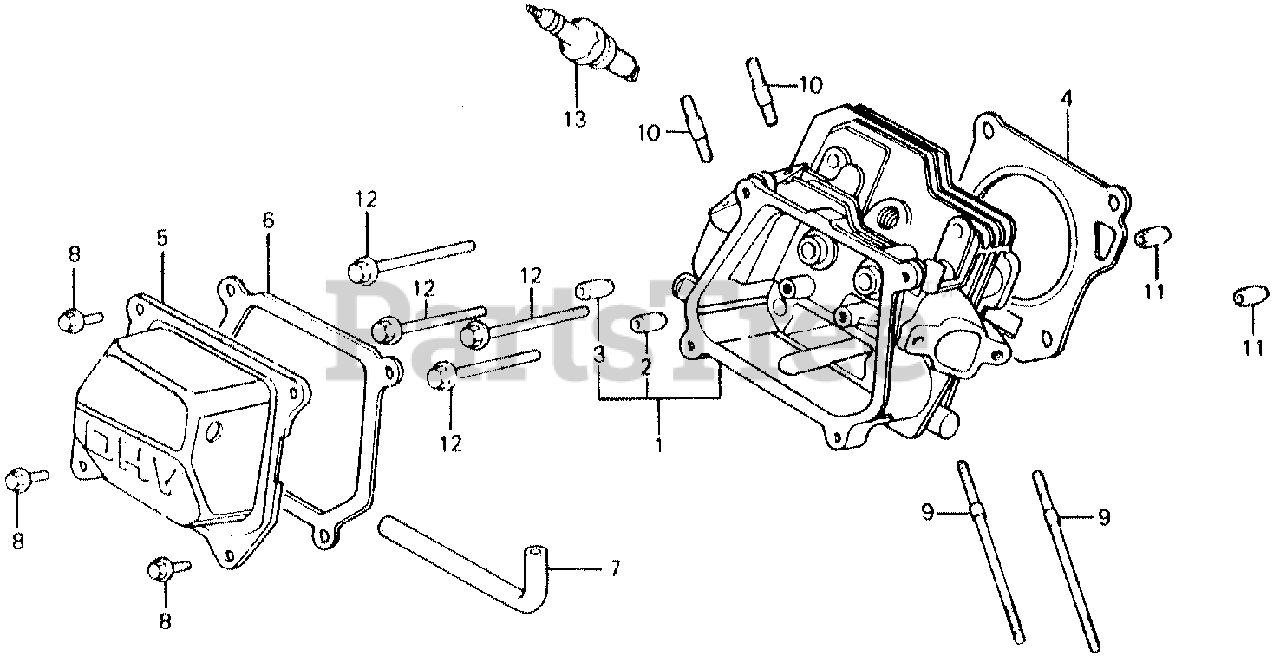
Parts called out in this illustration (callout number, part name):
1	CYLINDER HEAD
2	GUIDE, VALVE (OS)
3	GUIDE, EX. VALVE (OS)
4	GASKET, CYLINDER HEAD
5	COVER, HEAD
6	GASKET, CYLINDER HEAD COVER
7	TUBE, BREATHER
8	BOLT, FLANGE (6X13)
9	BOLT, STUD (6X109)
10	BOLT, STUD (8X32)
11	PIN A, DOWEL (10X16)
12	BOLT, FLANGE (8X60)
13	SPARK PLUG (BPR6ES) (NGK)
13	SPARK PLUG (W20EPR-U) (DENSO)
